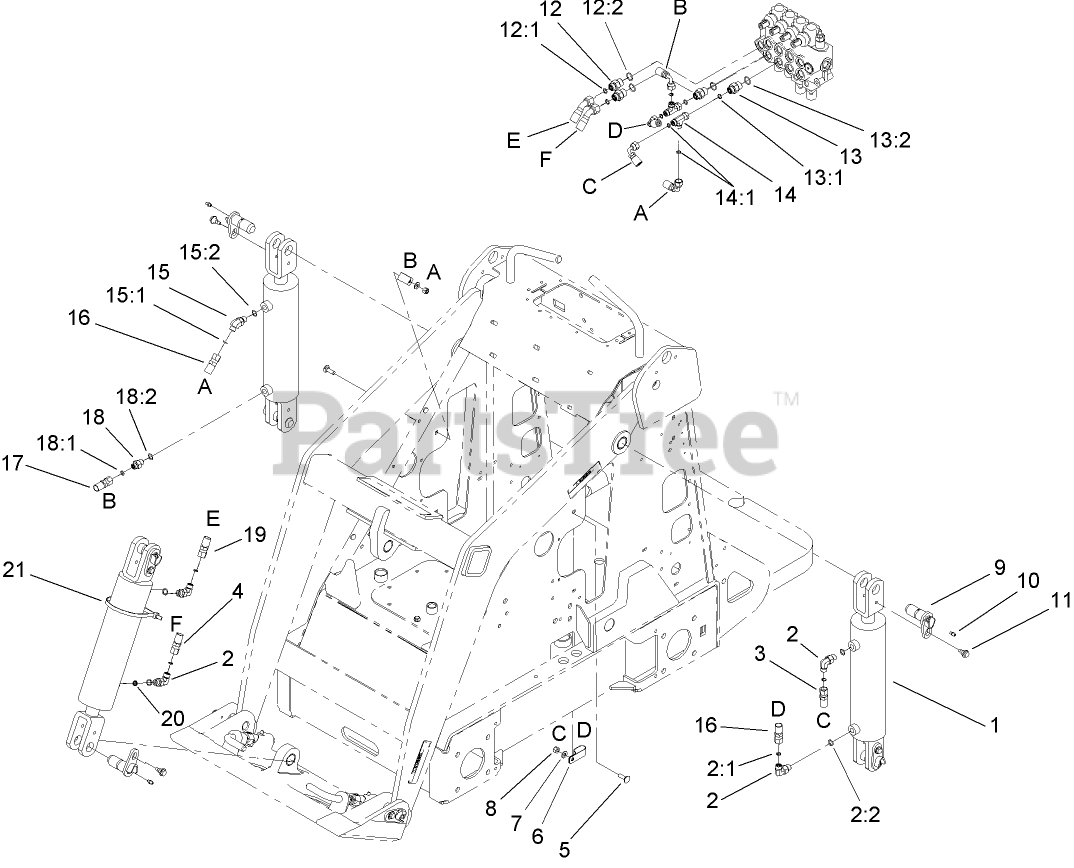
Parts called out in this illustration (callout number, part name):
1	HYD CYLINDER ASM
2	FITTING-ELBOW 90
2:1	O-RING
2:2	O-RING
3	HYD HOSE ASM
4	HOSE-HYD
5	BOLT-CARR
6	CLAMP-R, DOUBLE
7	WASHER-PLAIN
8	NUT-LOCK, NI
9	PIN-PIVOT
10	FITTING-GREASE
11	BOLT-SHOULDER
12	FITTING-STRAIGHT
12:1	O-RING
12:2	O-RING
13	FITTING-STR
13:1	O-RING
13:2	O-RING
14	FITTING-HYD
14:1	O-Ring
15	FITTING
15:1	O-RING
15:2	O-RING
16	HOSE-HYD
17	HOSE-HYD, RIGHT
18	FITTING-STRAIGHT
18:1	O-RING
18:2	O-RING
19	HOSE-HYD
20	ORIFICE-PORT INSERT, ONE WAY
21	TIE-CABLE
